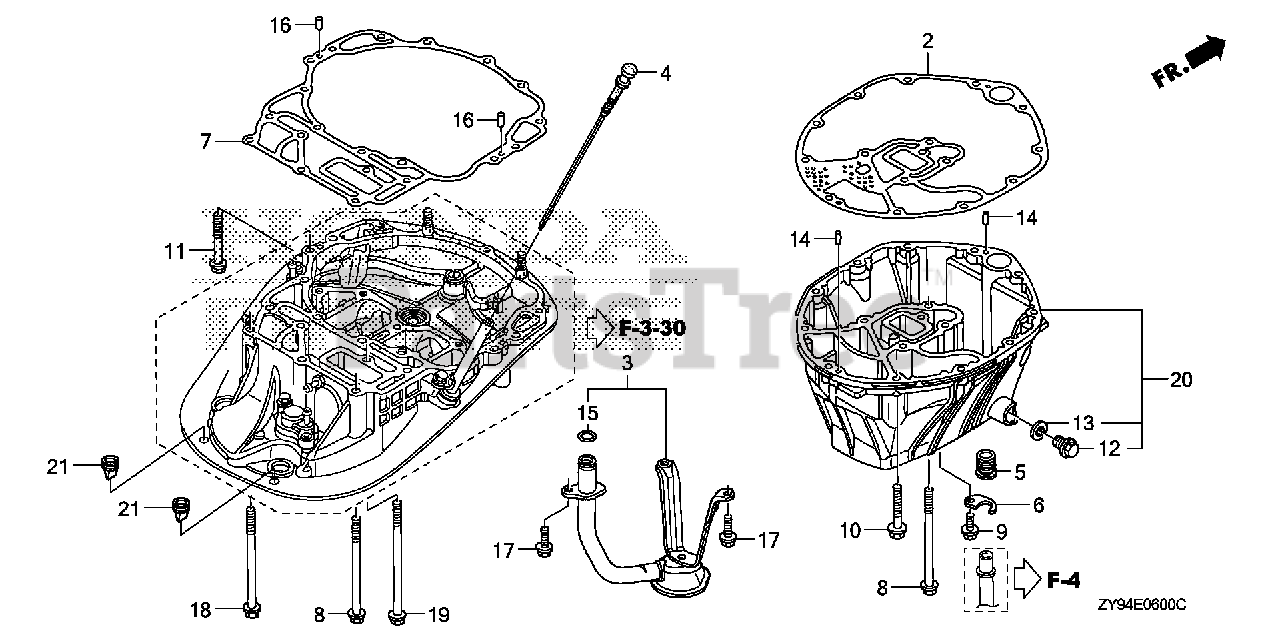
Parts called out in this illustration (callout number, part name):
2	GASKET, OIL PAN
3	STRAINER, OIL
4	DIPSTICK, OIL
5	GROMMET, WATER TUBE
6	PLATE, WATER TUBE
7	GASKET, MOUNT CASE
8	BOLT, FLANGE (8X100)
9	BOLT, FLANGE (6X12) Use from Frame SN 1005249.
10	BOLT, FLANGE (8X35)
11	BOLT, FLANGE (8X45)
12	BOLT, DRAIN PLUG
13	WASHER, DRAIN PLUG (12MM)
14	PIN, DOWEL (6X10)
15	O-RING (15.5X2.7)
16	PIN A, DOWEL (6X10)
17	BOLT, FLANGE (6X16)
18	BOLT, FLANGE (8X100)
19	BOLT, FLANGE (8X120)
20	CASE ASSY., OIL *TGRAY* (GRAY)
21	GROMMET (1WAY)
